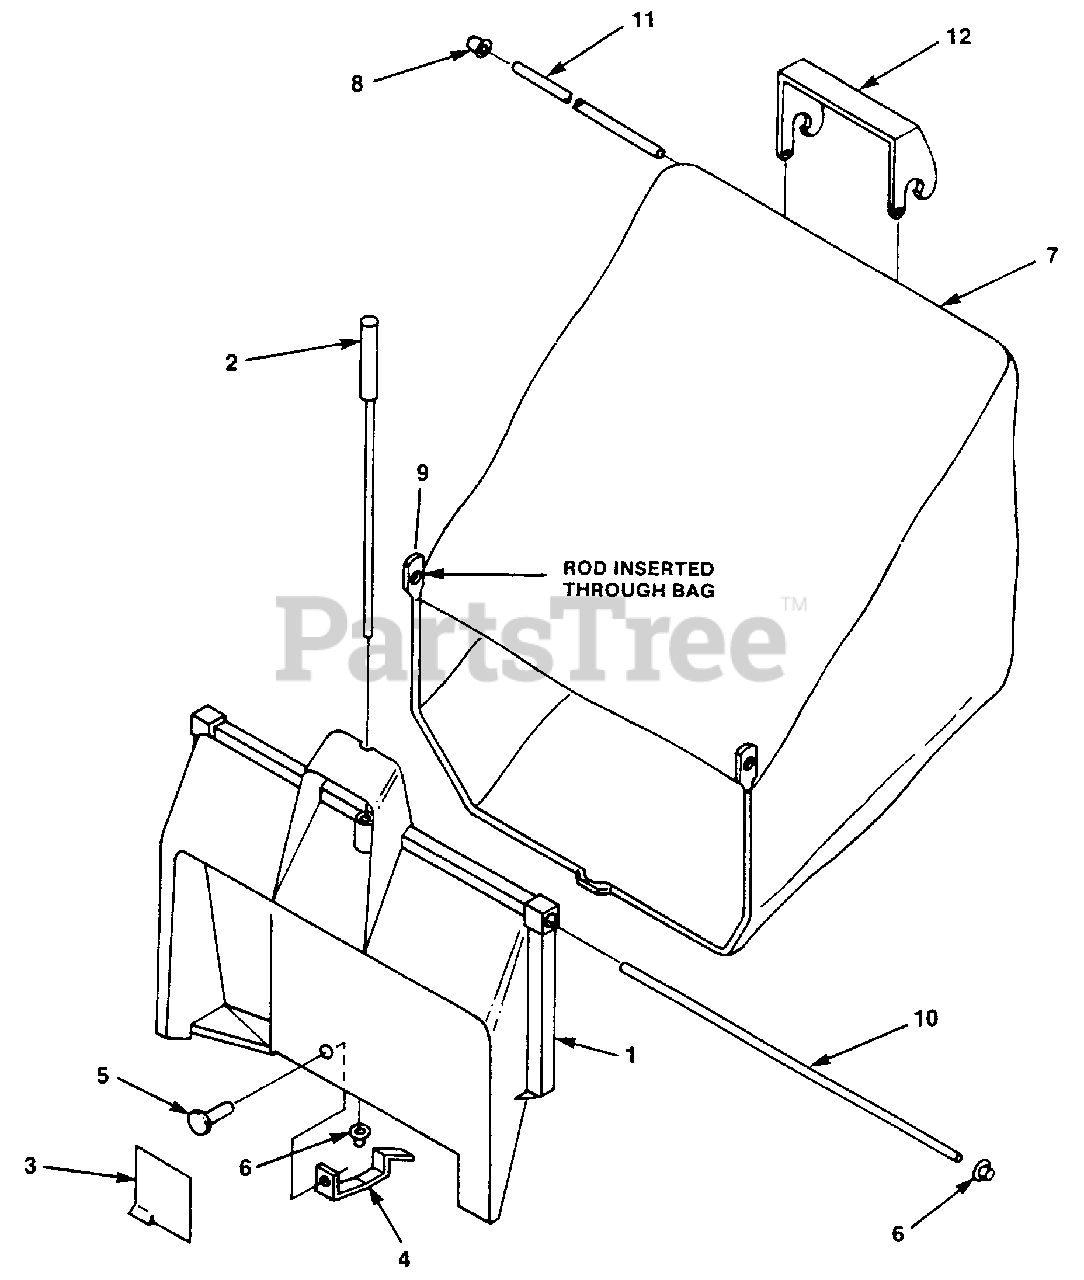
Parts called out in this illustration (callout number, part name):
1	ADAPTOR- Bag
2	ROD- Latch release
3	DEFLECTOR
5	RIVET- Pop 5/32 x 3/8"
7	GRASS BAG
9	ROD- Bag support
10	ROD- Bag hinge
11	ROD- Upper bag
12	HANDLE- Upper bag
